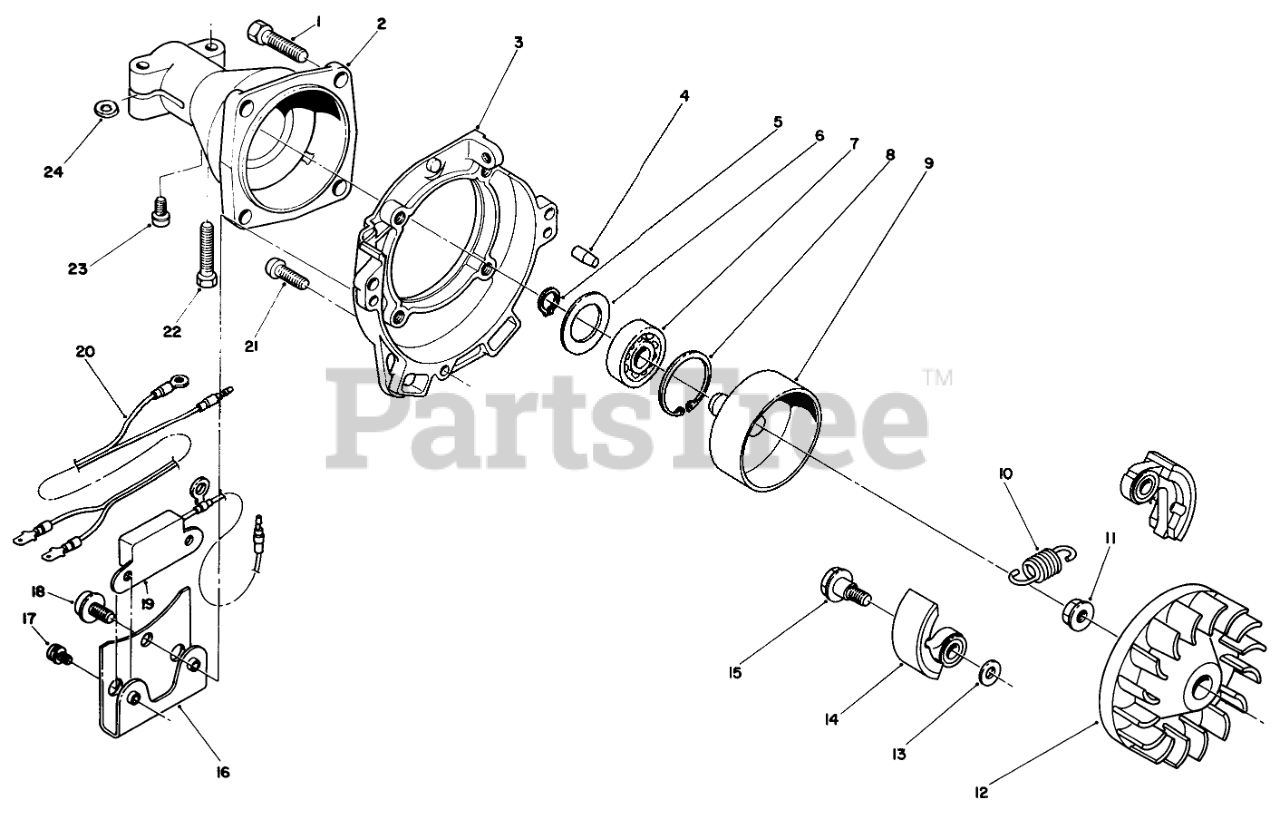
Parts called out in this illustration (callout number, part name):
1	Bolt/Washer
2	CLUTCH CASE
3	Case, Fan
5	SNAP RING
6	Washer
7	BALL BEARING
8	SNAP RING
9	CLUTCH DRUM
10	Spring
13	WASHER
14	SHOE, CLUTCH
15	CLUTCH BOLT
16	Bracket-Unit
17	SCREW W/ WASHER
18	SCREW & WASHER
19	TRANSISTOR
20	WIRE,LEAD
21	BOLT & WASHER
22	BOLT-WASHER/ENG
23	Screw/Washer
24	WASHER
